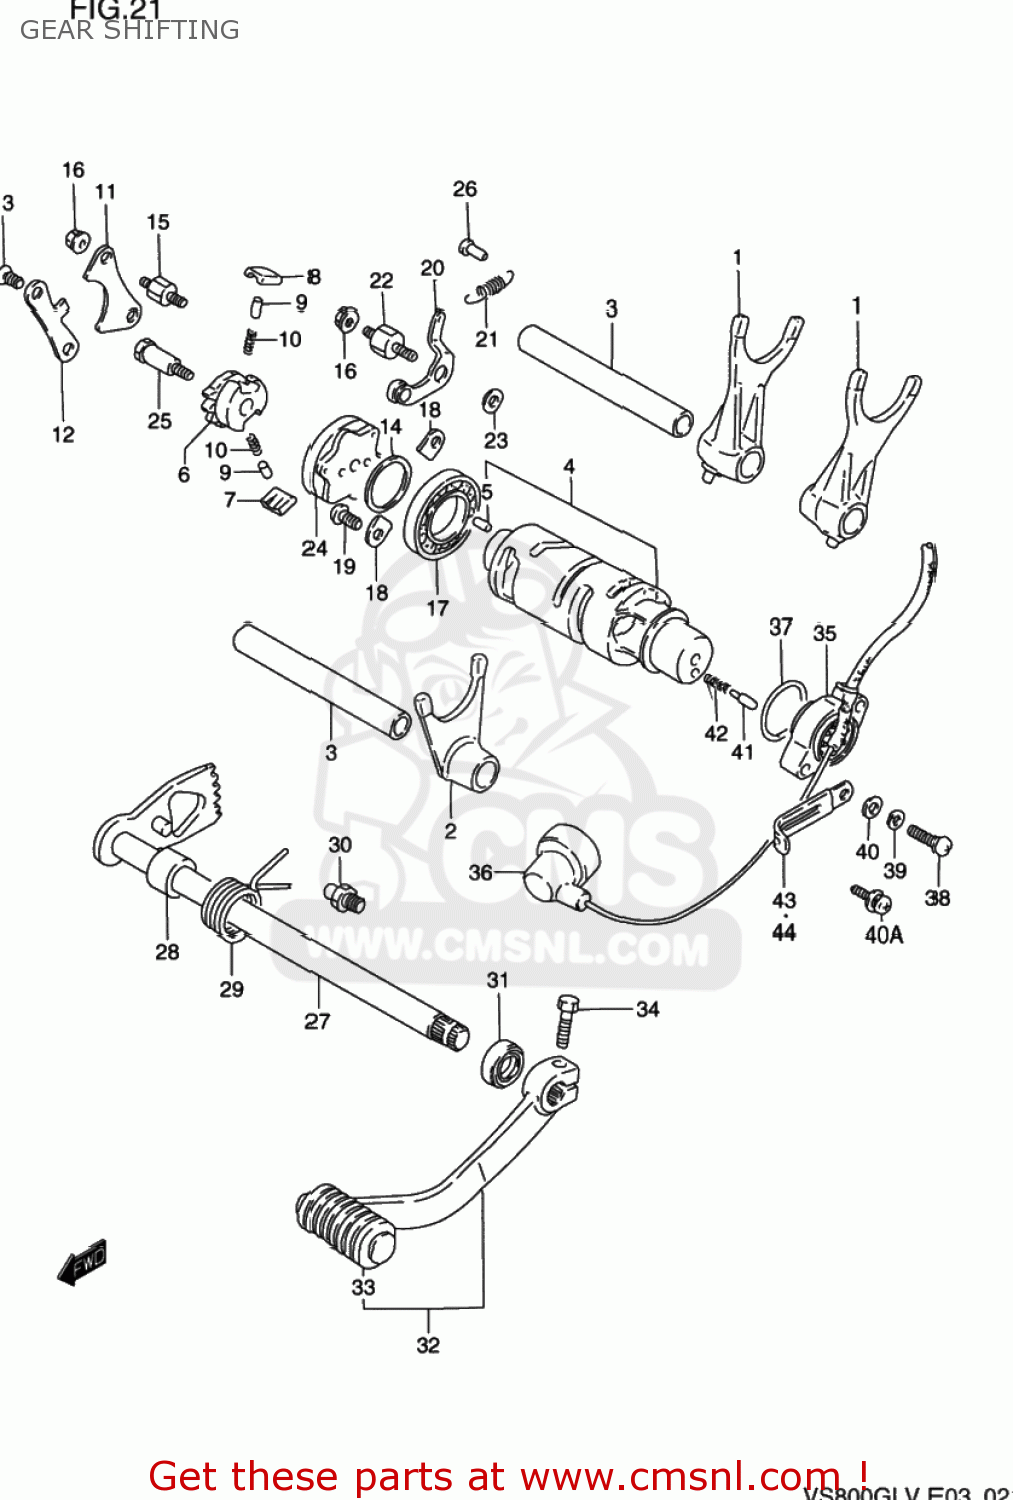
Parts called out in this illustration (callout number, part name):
1	FORK,GEAR SHIFT NO.1
2	FORK,GEAR SHIFT NO.2
3	SHAFT,GEAR SHIFT FORK(L:115)
4	CAM,GEAR SHIFT
5	PIN
6	GEAR,GEARSHIFT CAM DRIVE
7	PAWL,GEAR SHIFT NO.1
8	PAWL,GEAR SHIFT NO.2
9	PIN(5X8)
10	SPRING
11	LIFTER,GEAR SHIFT POLE
12	GUIDE,GEAR SHIFT CAM
13	SCREW
14	WASHER(25X32X3)
15	BOSS,SHIFT PAWL LIFTER
16	NUT
17	BEARING
18	RETAINER
19	SCREW
20	STOPPER,GEAR SHIFT CAM
21	SPRING
22	SUPPORT,CAM STOPPER ARM
23	WASHER
24	PLATE,GEAR SHIFT CAM
25	PIN,SHIFT CAM DRIVEN GEAR
26	RIVET
27	SHAFT,GEAR SHIFT
28	SPACER(12X20X15.3)
29	SPRING
30	STOPPER,GEAR SHIFT CAM
31	OIL SEAL
32	LEVER ASSY,GEAR SHIFT
33	RUBBER,GEAR SHIFT PEDAL
34	BOLT
35	BASE,NEUTRAL SWH TERMINAL
36	CAP,OIL PRESSURE SWITCH
37	O RING(D:2.4,ID:26.2)
38	SCREW
39	WASHER,LOCK
40	WASHER
40A	SCREW
41	PIN(5X15.5)
42	SPRING
43	CLAMP
44	CLAMP
